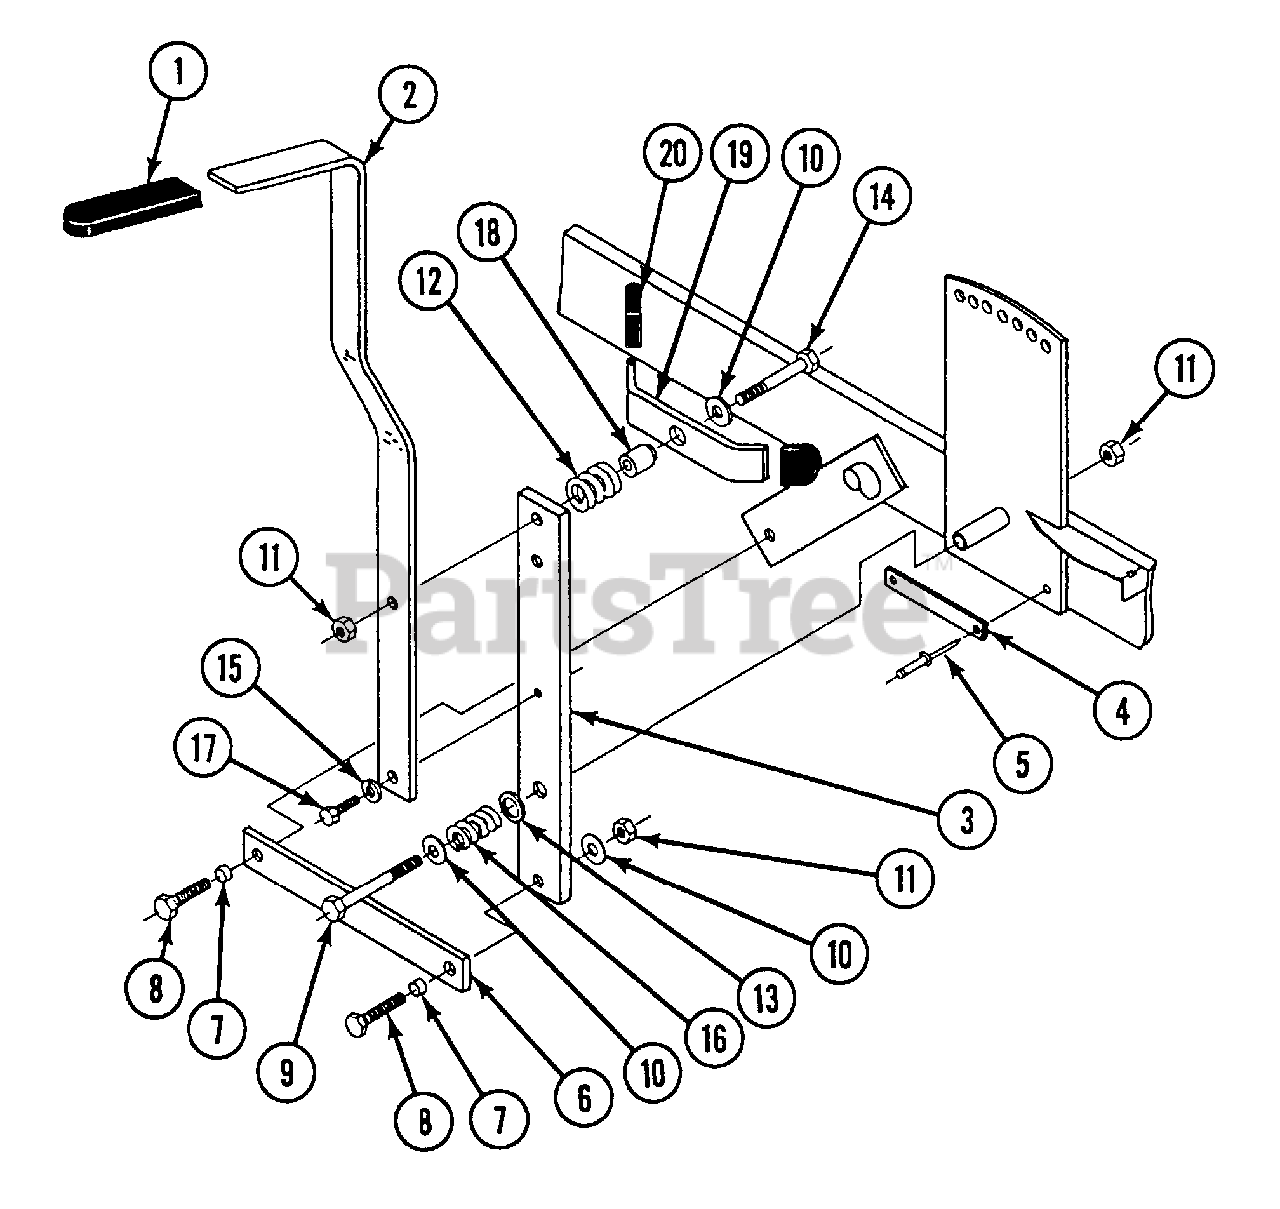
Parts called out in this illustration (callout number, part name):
1	GRIP, VINYL, 1/4 X 1
2	HANDLE, TOP DECK LIFT
3	DECK HANDLE WELDMENT
4	DECK LATCH SLIDE (EARLIER MODELS)
5	RIVET, BLIND POP (EARLIER MODELS)
6	DECK LIFT CONNECTOR
7	BUSHING, CONNECTOR
8	CAPSCREW, HX HD: 3/8-16 X 1-1/4 GR 5
9	CAPSCREW, HX HD: 3/8-16 X 2-3/4 GR 5
10	FLAT WASHER: 3/8
11	NUT, NYLOC: 3/8-16
12	SPRING, COMPRESSION
13	WASHER, 8 GA: .656 I.D. X 1 O.D.
14	CAPSCREW, HX HD: 3/8-16 X 2 GR 5
15	LOCKWASHER, SPLT SPRNG: 5/16
16	SPRING, COMPRESSION
17	CAPSCREW, HX HD: 5/16-18 X 3/4 GR 5
18	LOCK STAND
19	LOCK ARM
20	GRIP, LOCK
